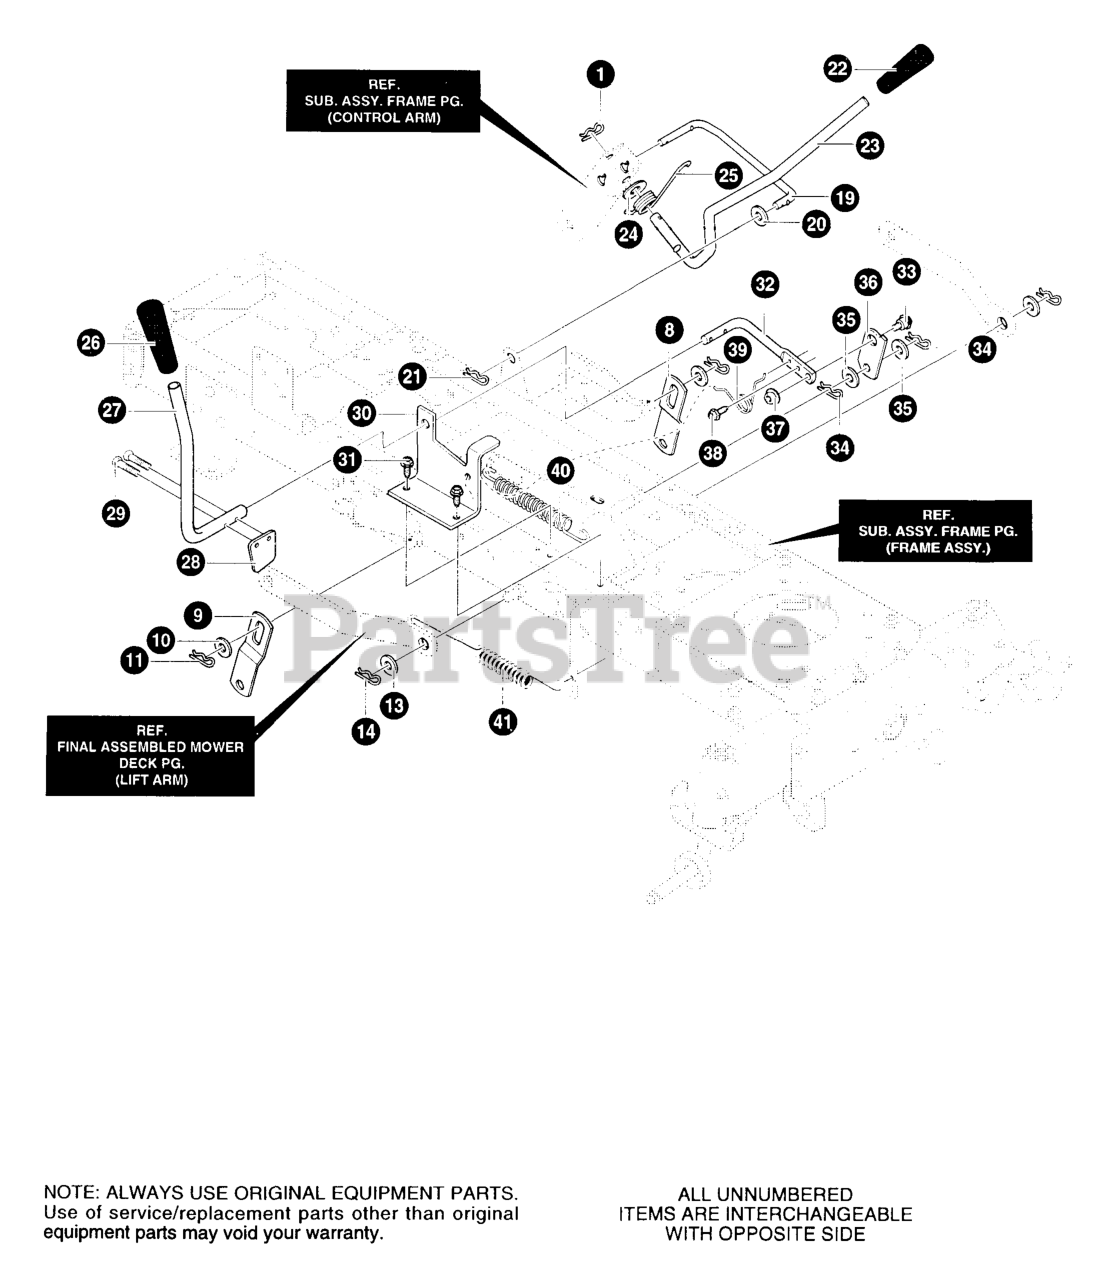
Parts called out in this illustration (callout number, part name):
1	HAIR PIN
8	LINK, LIFT LH
9	LINK-LIFT
10	FLATWASHER
11	PIN, HAIR
13	WASHER, FLAT
14	PIN, HAIR
19	LINK LIFT HANDLE
20	WASHER, FLAT
21	PIN, HAIR
22	GRIP, LIFT 1/2"
23	HANDLE, LIFT
24	WASHER, FLAT .550 x 1.00 x 11
25	TORSION SPRING,.657LG
26	Grip, PTO
27	HANDLE, PTO
28	PADDLE SWITCH
29	SCREW, THD FORM .246X1.050LG
30	BRACKET, PTO
31	SCREW, 5/16-18 x 0.50 HHWATAP
32	LEVER, PTO
33	BOLT, .50X.75 HHSH 3/8-16
34	PIN, HAIR.072 DIAX1.13LG
35	WASHER, FLAT .518 x .87 x 16
36	LINK PTO
37	NUT, 3/8-16 HWDFLLK MACK
38	SCREW, 5/16-18 x 0.75 HHWATAP
39	TORSION SPRING.33LG
40	SPRING, TENSION 1.01OD 8.18LG
41	EXTENSION SPRING
